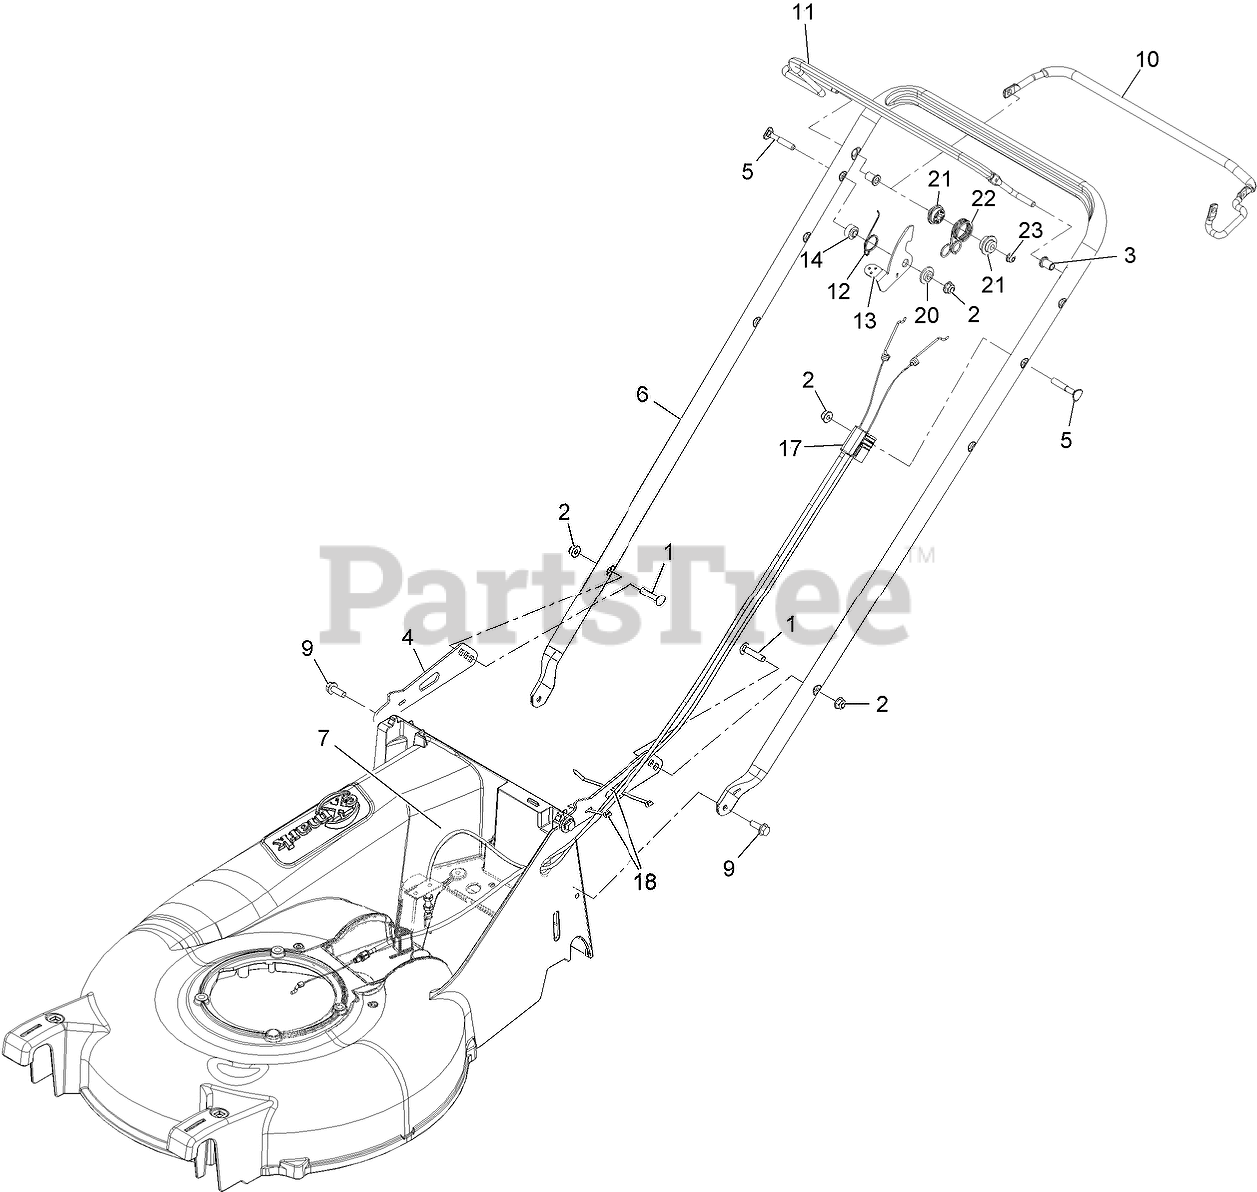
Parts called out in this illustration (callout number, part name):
1	BOLT-CARR
2	NUT-HF, NI
3	BUSHING-HANDLEBAR
4	BRACKET,HANDLEBAR
6	HANDLEBAR-P21
7	CABLE, DRIVE EC21
9	SCREW-TAPTITE
10	BAIL-DRIVE COATED
12	SPRING-LEVER, BBC
13	LEVER-BBC
14	BUSHING-STEPPED
17	CABLE-BBC
18	TIE-CABLE
20	WASHER-STEPPED
21	BUSHING-SPRING, PIVOT
22	SPRING,BBC RETURN
